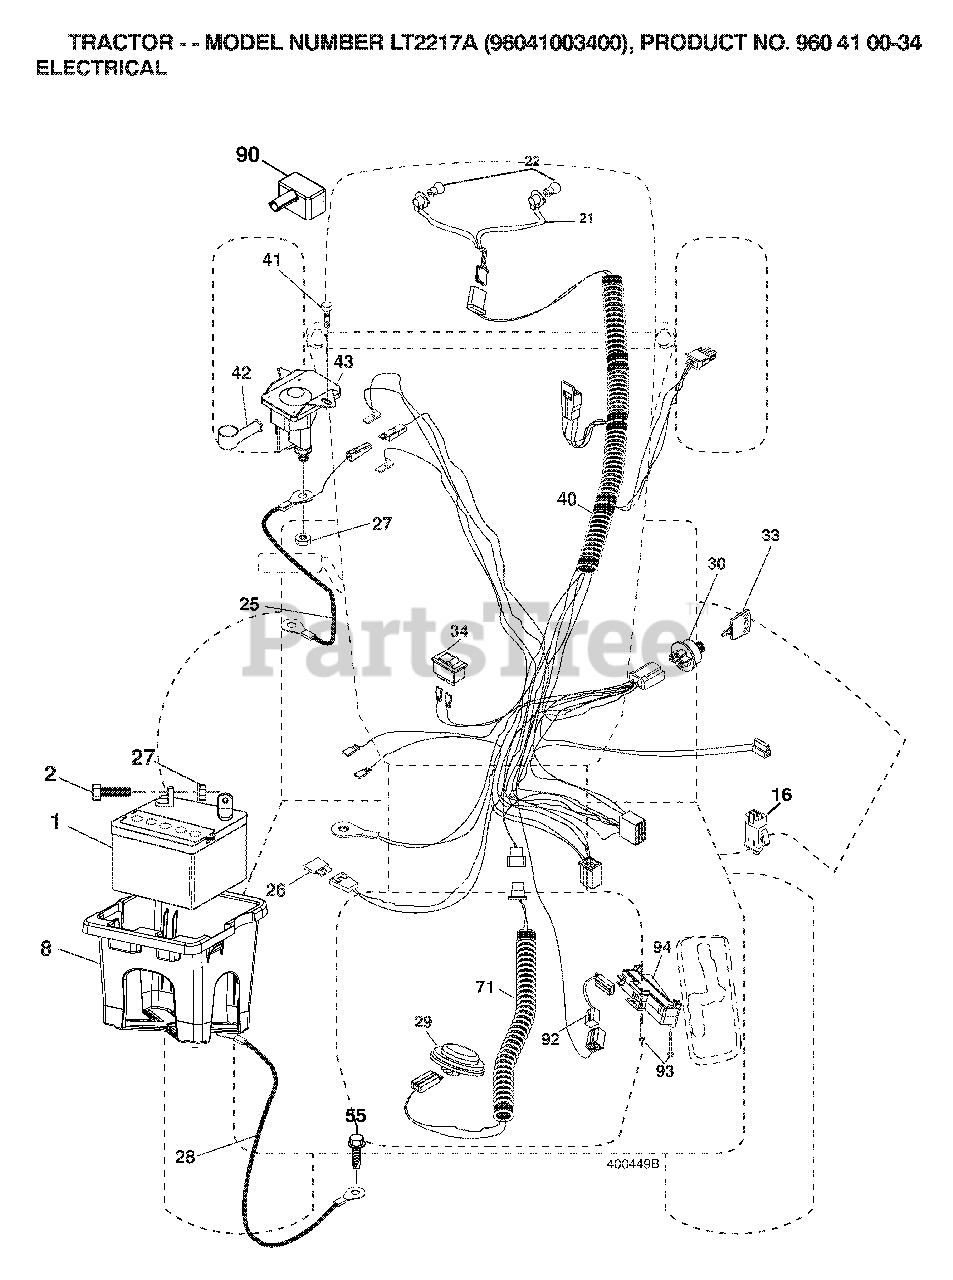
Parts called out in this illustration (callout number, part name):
1	BATTERY 12V .35 AMP
8	BOX.BATTERY.MNT.REAR.L
16	SWITCH INTERLOOK PUSH-IN
21	HARNESS ASSY LIGHT
22	LIGHTBULB
25	CABLE.STARTER.6GA.RED.
26	FUSE 20AMP
27	NUT
28	CABLE.BLACK.18"REAR.BA
29	SWITCH.SEAT.DELTA.OPC.
30	SWITCH.IGN.DELTA.W.LGH.ROS
33	KEY MLD GEN DELTA
34	SWITCH LT
40	HARNESS.IGN.CHASS.TEX.REAR.BAT
41	SCREW
42	TERMINAL COVER
43	SOLENOID.W/BRASS.PLUNG
55	SCREW 5/16"
71	HARNESS IGN. DASH
79	BULB HOLDER ASM.
87	SWITCH.INTRLCK.CLUTCH.
90	COVER, TERMINAL BATTERY
92	HARNESS.PIGTAIL.CONSLE
93	SCREW.PLASTITE
94	MODULE.REVERSE.ROS
